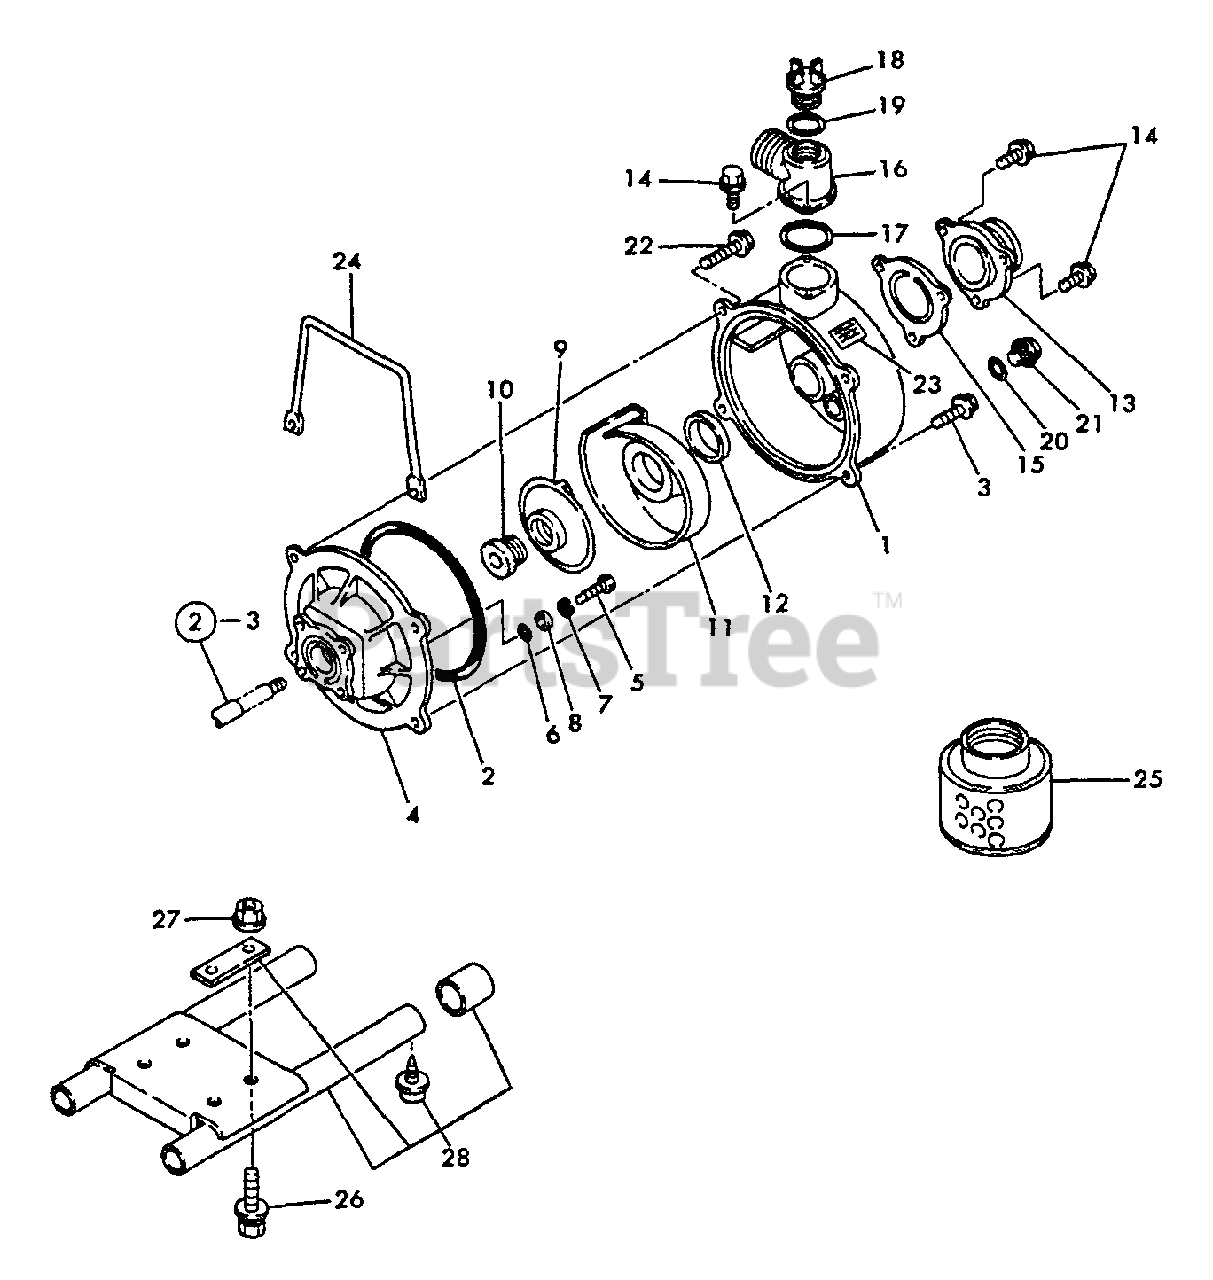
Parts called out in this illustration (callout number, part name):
1	CASING
2	GASKET, CASING
3	BOLT - 8×25
4	COVER, CASING
5	BOLT - 8×48
7	LOCKWASHER
8	WASHER - 8
9	IMPELLER
10	SEAL, MECHANICAL
11	CASING, INNER
12	GASKET, INNER CASING
13	CASE
14	BOLT M6×20
15	VALVE, CHECK
17	GASKET, BEND
19	GASKET, PLUG
20	GASKET, DRAIN
21	BOLT, DRAIN - 12×20
22	BOLT - 8×40
23	LABEL - MODEL
24	HANDLE
25	STRAINER, DEBRIS
26	BOLT - 8×45
27	NUT - 8
